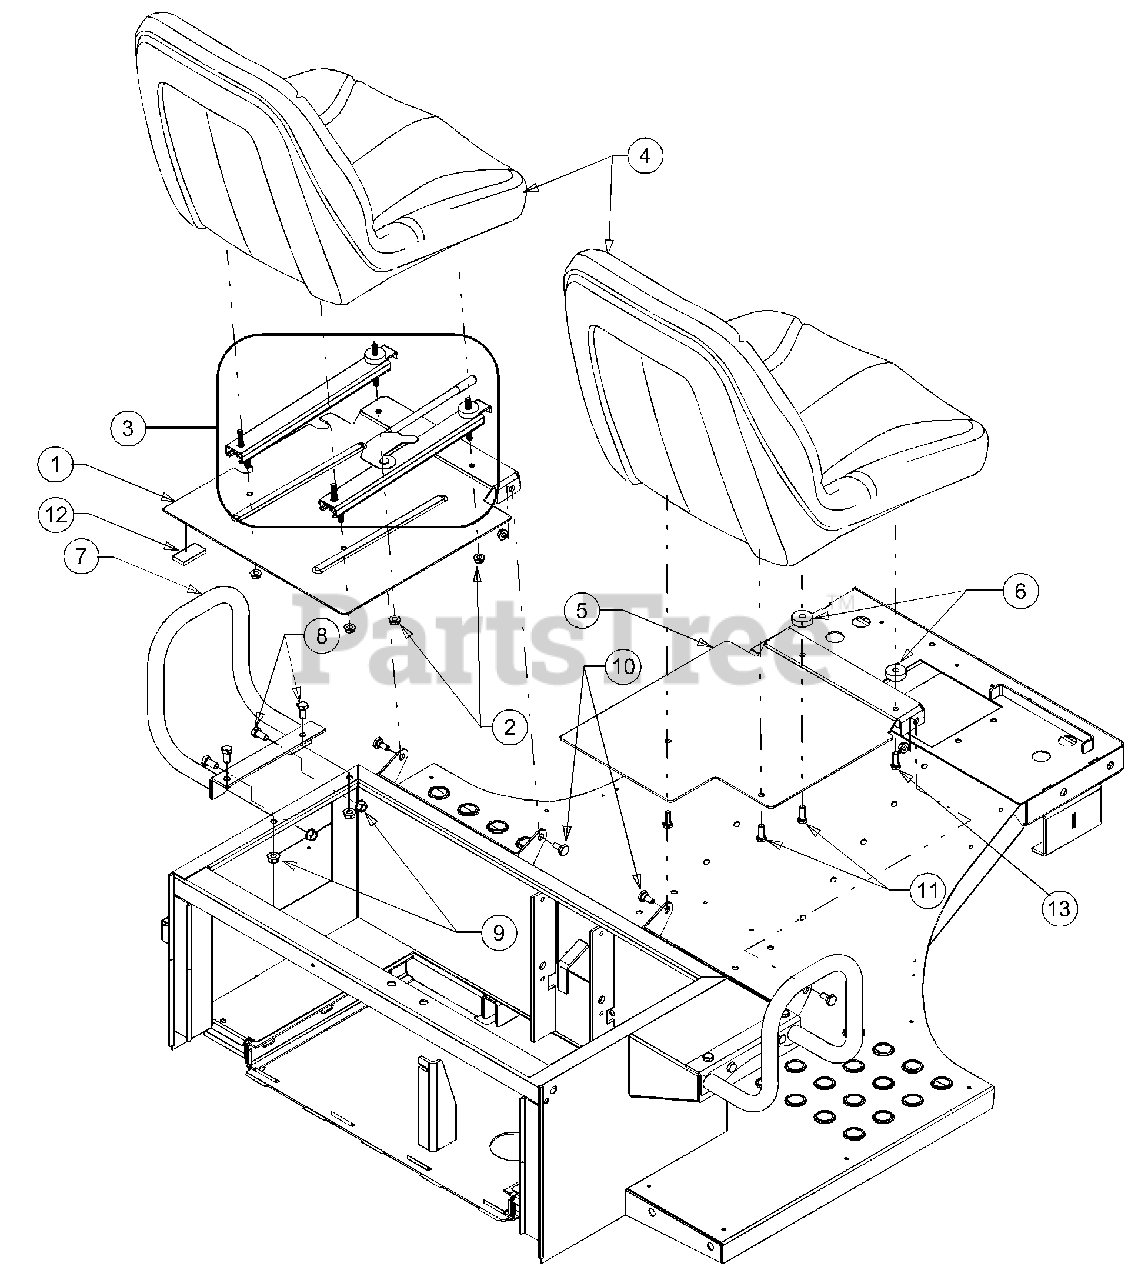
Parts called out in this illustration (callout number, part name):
1	Plate Assembly, Seat, LH
2	Nut, Flange Lock, 5/16-18, Gr5
3	Track Assembly, Seat
4	Seat
5	Plate Assembly, Seat, RH
6	Spacer, Seat
9	Nut, Flange Lock, 3/8-16
10	Shoulder Screw, .435 x .178-5/16 x .56
11	Hex Screw, 5/16-18 x .625, Gr5
12	Bumper .62 Dia x .3
13	Hex Screw 5/16-18 x 1.00 Gr 5
